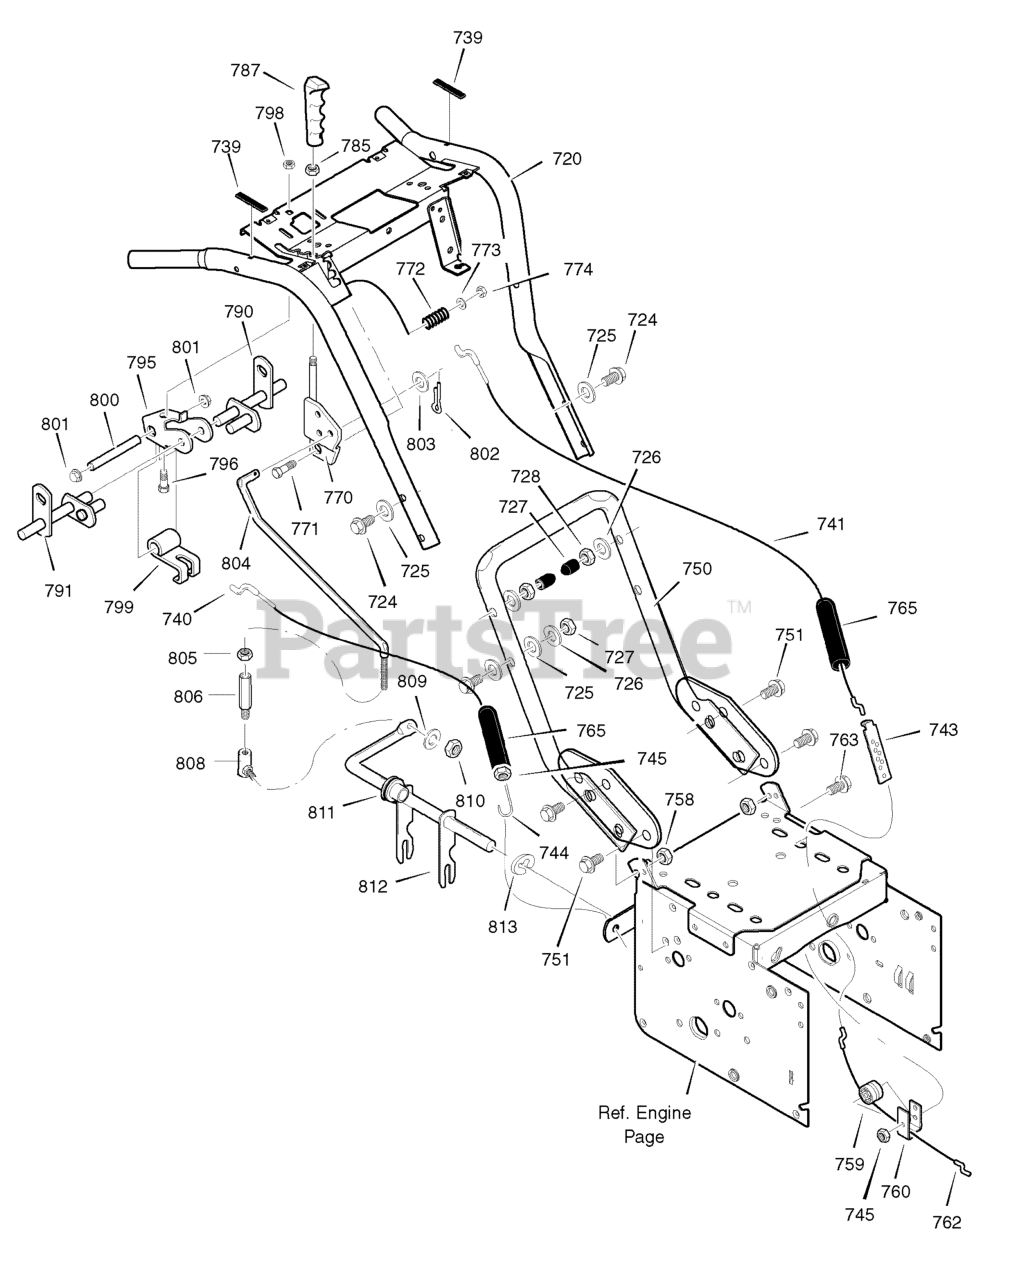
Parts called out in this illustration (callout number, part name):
720	HANDLE ASSEMBLY
724	SCREW
725	WASHER, Flat, 13/32
726	WASHER
727	NUT
728	STOP, PLASTIC
739	BUMPER
740	CABLE, AUGER CLUTCH
741	CABLE, DRIVE
743	BRACKET, CABLE ADJUST
744	SPRING, CLUTCH
745	NUT, HEX
750	HANDLE, LOWER
751	SCREW
758	NUT, HEX, 5/16-18 YZ
759	SPOOL, CABLE
760	BRACKET, SPOOL
762	CABLE, LOWER DRIVE
763	BOLT, HEX 1/4-20 X 1.5
765	BOOT, CABLE
770	BRACKET, SHIFT
771	SCREW
773	WASHER, Flat, 13/32
774	NUT, HEX
785	NUT, HEX
787	KNOB, SHIFT
790	ROD, ASSEMBLY LH
791	ROD, ASSEMBLY RH
795	BRACKET, CAM
796	SCREW
798	NUT, NYLOCK
799	CAM LOCK
800	PIN, SPRING PIVOT
801	NUT, PUSH ON
802	PIN, COTTER
803	FLATWASHER
804	ROD, SPEED CONTROL
805	NUT, 5/16-18
806	ADAPTER, ROD
808	BALLJOINT, STEEL
809	WASHER
810	NUT, 5/16-18
811	BEARING, FLANGE
812	ROD, YOKE
813	RETAINER, RING
